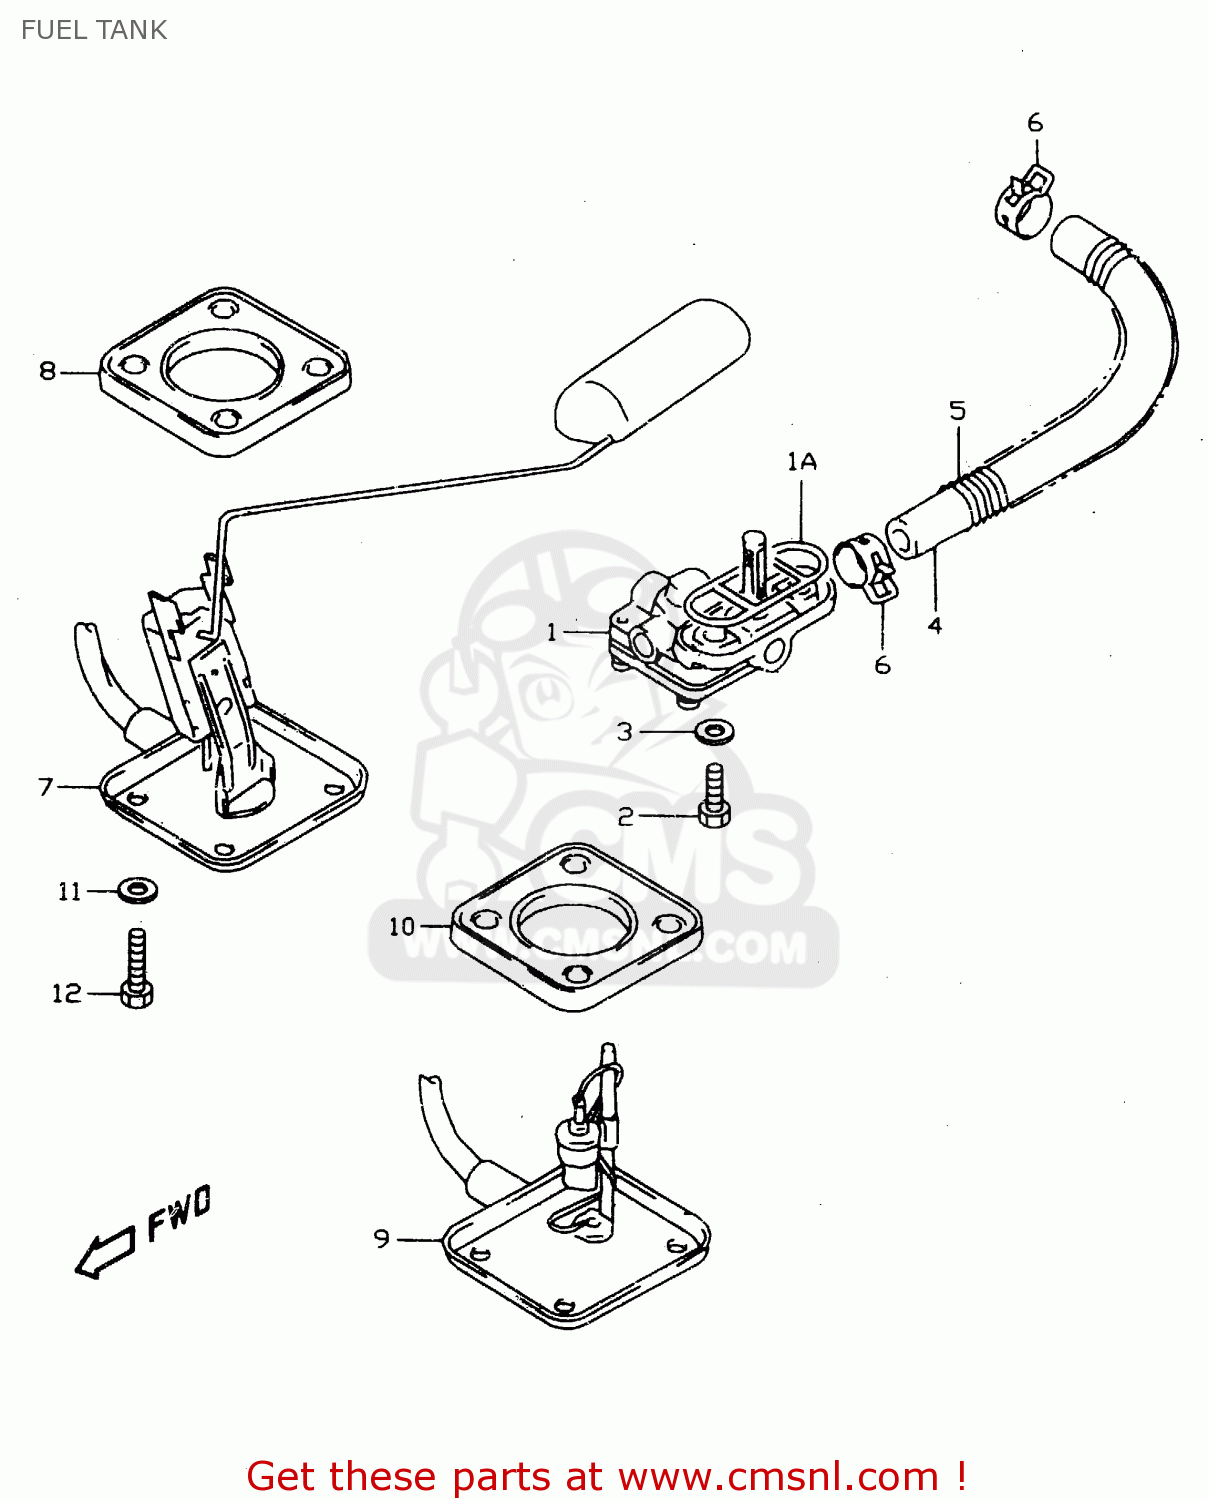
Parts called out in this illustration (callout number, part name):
1	COCK ASSY, FUEL
1A	O RING,JOINT
2	BOLT(6X20)
3	GASKET(6.4X11.5X0.8) (NAS)
4	HOSE(7X12X600)
5	SPRING
6	CLIP
7	GAUGE ASSY,FUEL LEVEL
8	PACKING (NAS)
9	GAUGE ASSY,FUEL LEVEL
10	PACKING (NAS)
11	GASKET(6.4X11.5X0.8) (NAS)
12	BOLT(6X20)
